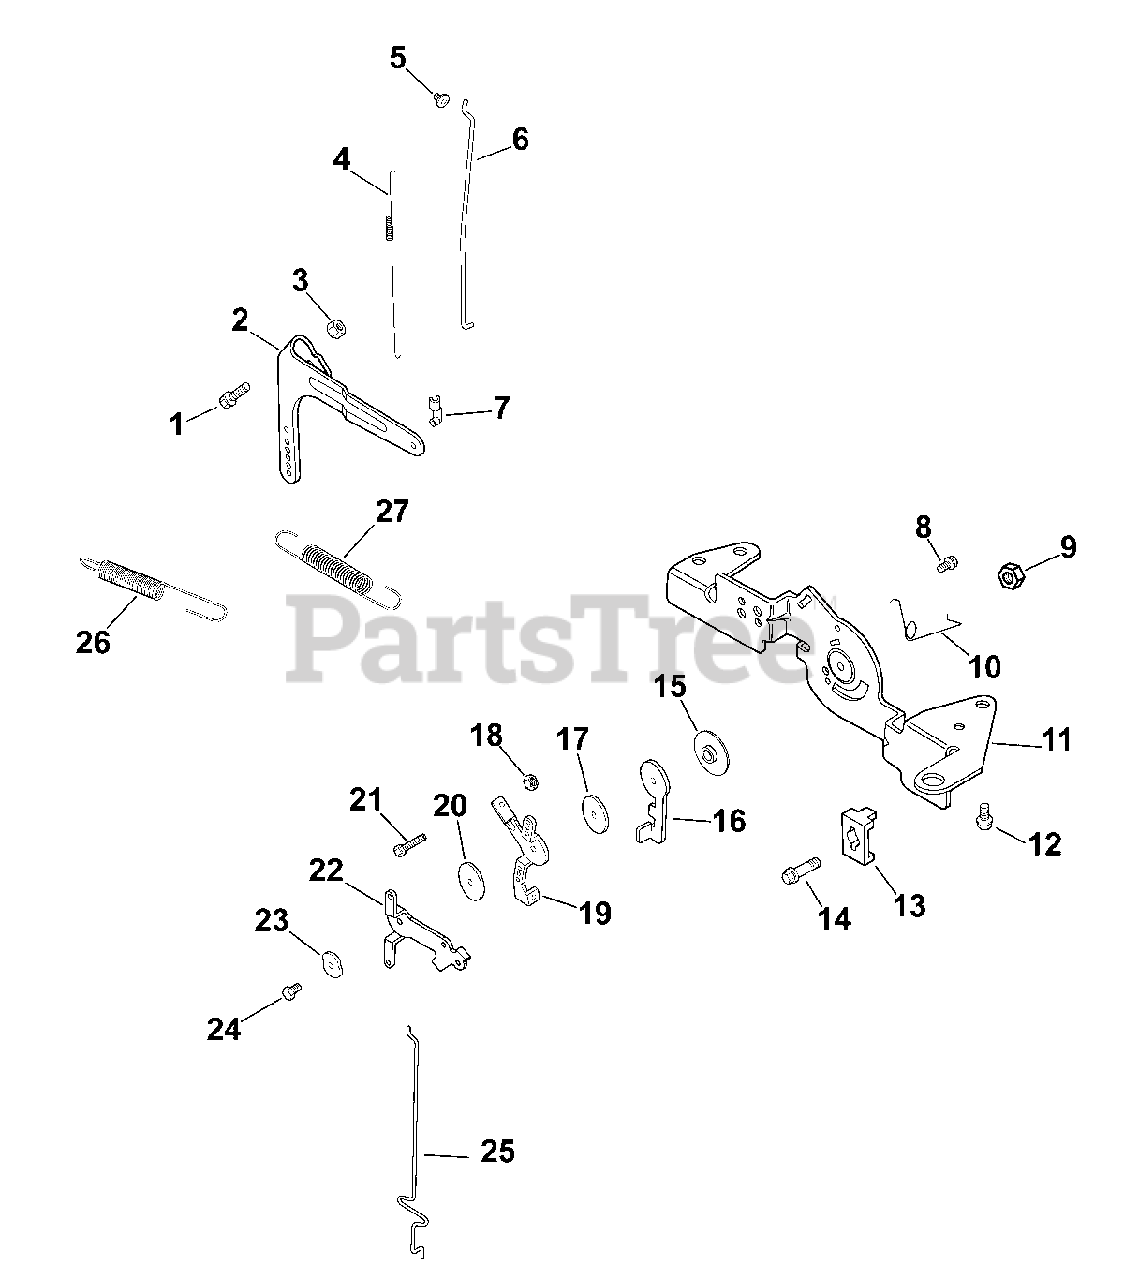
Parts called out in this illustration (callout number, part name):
1	BOLT, RD HD SQ NECK M6X1.0X25
2	LEVER, GOVERNOR-USE 24 090 57-S
3	NUT, FLG M6X1.0
4	SPRING, LINKAGE
5	BUSHING, LINKAGE RETAINING
6	LINKAGE, THROTTLE
7	BUSHING, THROTTLE LINKAGE
8	SCREW,FLG THD FRM M5X0.8X16-(#25086398S)
9	NUT, LOCK M5X.8
10	SPRING, CHOKE RETURN
11	BRACKET, CONTROL-USE 24 126 176-S
12	SCREW,FLG THD FRM M6X1.0X16-(#25086397S)
13	CLAMP, CABLE
14	SCREW, LBD THD FRM M5x0.8x16 - USE 25 086 405-S
15	SPACER, CONTROL ASSEMBLY
16	LEVER, THROTTLE ACTUATOR
17	WASHER, FLAT 5 MM
18	NUT, M4X0.7
19	LEVER, THROTTLE CONTROL
20	WASHER, FLAT 5.5 MM
21	SCREW, FLG THD FRM M5X.8X20-(#25086399S)
22	LEVER, CHOKE
23	WASHER, SPRING 1/4"
24	SCREW, SLT HD CAP M4X0.7X25
25	LINKAGE, CHOKE
26	SPRING, GOVERNOR (ORANGE)
27	SPRING, GOVERNED IDLE
